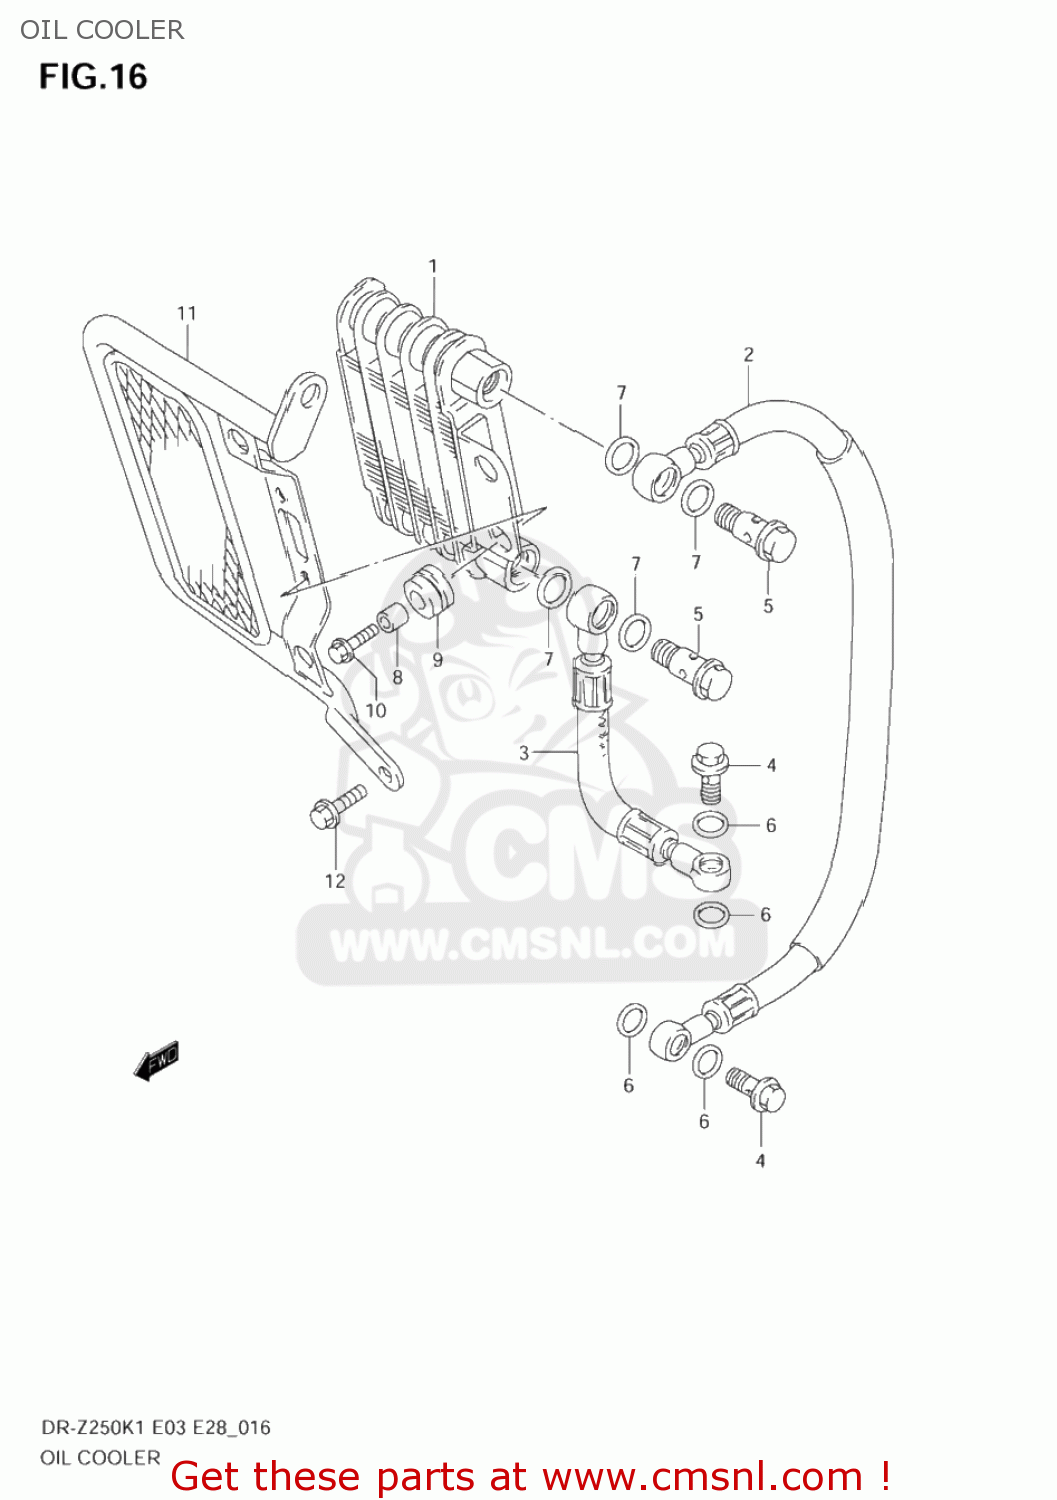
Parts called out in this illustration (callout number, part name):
1	COOLER ASSY,OIL
2	HOSE,OIL COOLER UPR
3	HOSE,OIL COOLER LWR
4	BOLT UNION
5	BOLT UNION
6	GASKET(10.1X16X1) (NAS)
7	GASKET(14X20X1.5) (NAS)
8	SPACER(6.5X10X10)
9	CUSHION
10	BOLT(6X20)
11	GUARD,OIL COOLER
12	BOLT
